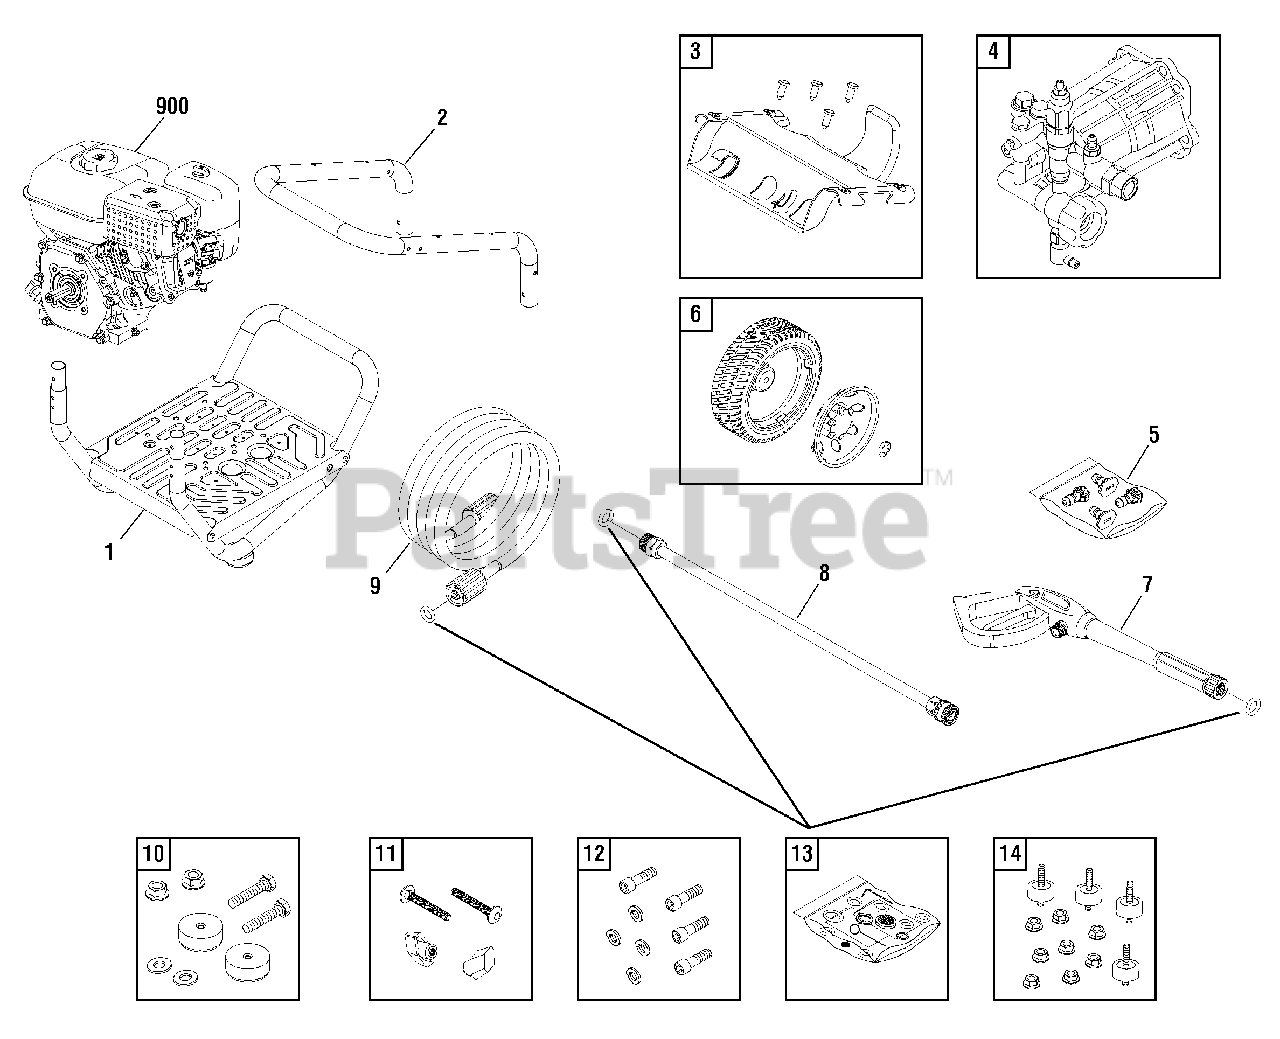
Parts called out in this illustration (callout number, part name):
5	KIT-QC NOZZLE
7	GUN
10	MOUNT-VIBRATION
11	KIT-HARDWARE HANDLE
12	KIT-HARDWARE PUMP MOUNTING
14	KIT-VIBRATION MOUNT
900	ENGINE
